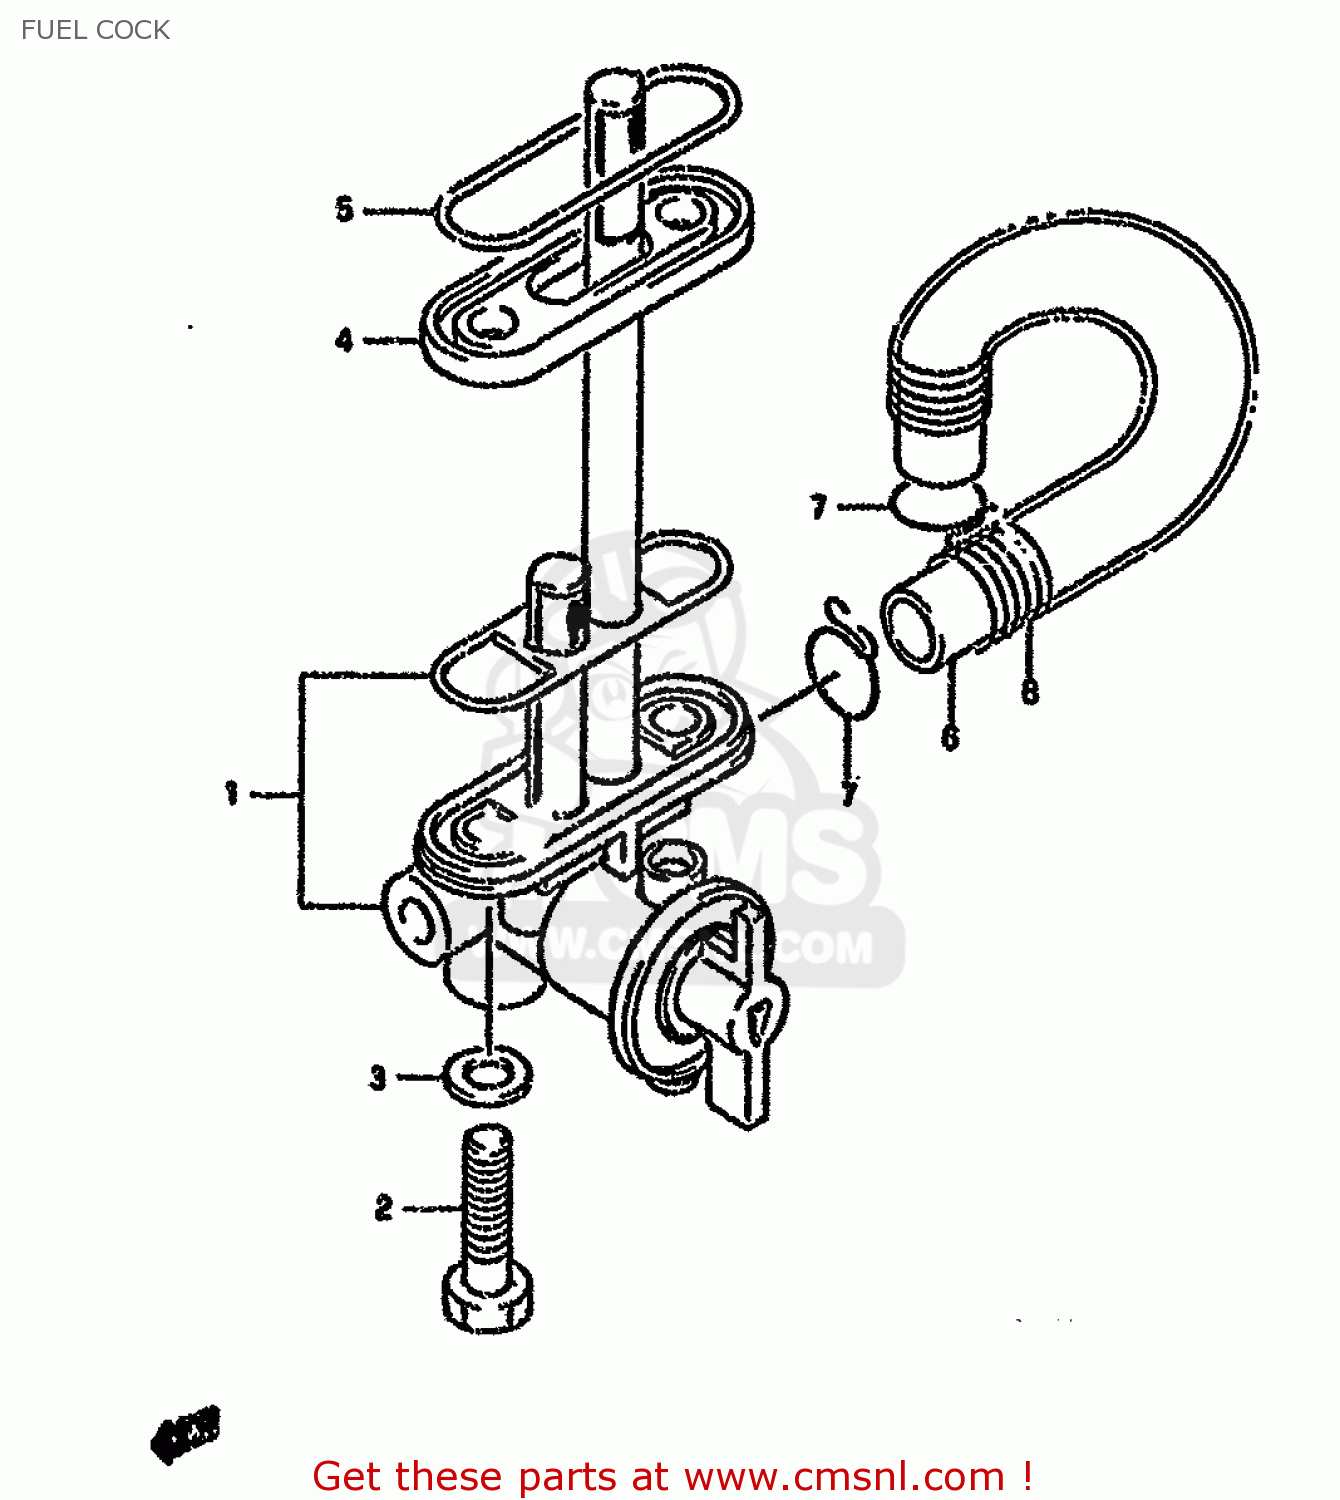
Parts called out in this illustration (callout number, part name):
1	COCK ASSY,FUEL
2	BOLT(6X20)
3	GASKET(6.4X11.5X0.8) (NAS)
4	SPACER,FUEL COCK
5	GASKET,FUEL COCK (NAS)
6	HOSE(7X10.2X600)
7	CLIP
8	(CA) SPRING
